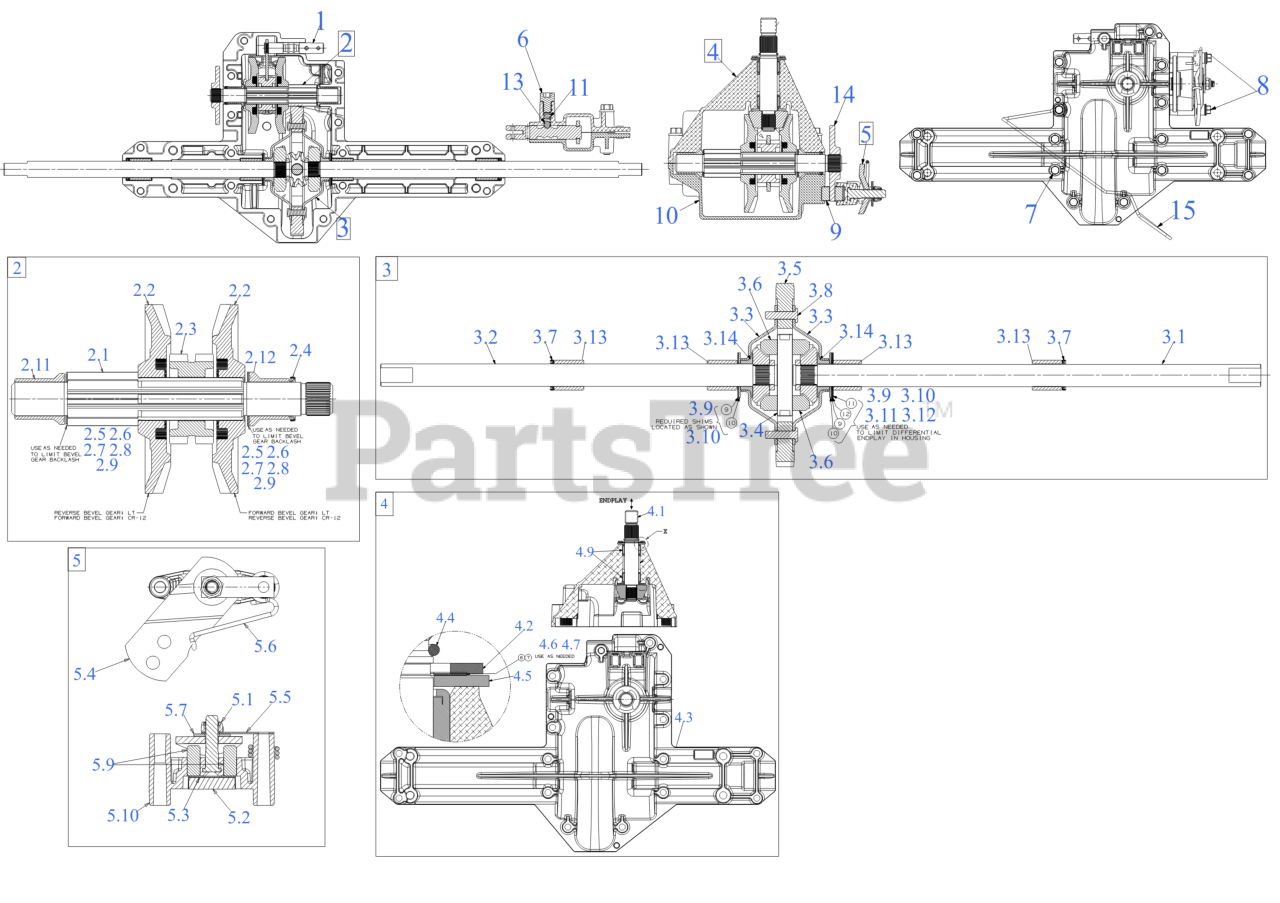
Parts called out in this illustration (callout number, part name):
1	DETENT SHAFT ASSEMBLY
2	FWD/REV SHAFT ASSEMBLY
2.1	Not Serviceable/ Order Complete Assembly
2.2	BEVEL GEAR 42T SPLINE
2.3	CLUTCH COLLAR
2.5	SHIM WASHER 0.627x1.030x0.030
2.6	SHIM WASHER 0.627x1.030x0.040
2.7	SHIM WASHER 0.627x1.005x0.020
2.8	SHIM WASHER 0.627x1.010x0.036
2.9	SHIM WASHER 0.627x1.010x0.025
2.11	FLANGE BEARING .625x.750x.938
2.12	FLANGE BEARING .625x.750x.750
3	DIFFERENTIAL
3.1	Not Serviceable/ Order Complete Assembly
3.2	Not Serviceable/ Order Complete Assembly
3.3	Not Serviceable/ Order Complete Assembly
3.4	CROSS PIN .500 x 2.75
3.5	Not Serviceable/ Order Complete Assembly
3.6	MITER GEAR 10T
3.8	Not Serviceable/ Order Complete Assembly
3.9	SHIM WASHER 0.755x1.505x0.030
3.10	THRUST WASHER 0.755x1.505x0.060
3.11	SHIM WASHER 0.755x1.505x0.010
3.12	SHIM WASHER 0.755x1.505x0.022
3.13	SLEEVE BEARING
3.14	FLANGE BEARING
4	UPPER HOUSING ASSEMBLY
4.1	INPUT SHAFT ASSEMBLY
4.1	THRUST WASHER
4.1	INPUT PINION GEAR 14T
4.3	Not Serviceable/ Order Complete Assembly
4.5	THRUST WASHER
4.6	SHIM WASHER 0.627x1.010x0.010
4.7	SHIM WASHER 0.627x1.010x0.007
4.9	NEEDLE BEARING
5	BRAKE ASSEMBLY
5.1	HEX JAM LOCK NUT 5/16-24
5.3	BRAKE PAD PLATE
5.4	BRAKE ACTUATING ARM
5.5	ANTI ROTATION BRACKET
5.6	TORSION SPRING
5.7	THRUST WASHER
5.9	ACTUATING PIN
5.10	BRAKE YOKE
6	SHCS:M8X1.25:10:GB/T 699-1999
7	HXFLG:M6X1:40:GR8.8
8	HXFLG:M6X1:58:GR8.8
10	HOUSING ASSEMBLY (LOWER)
11	DETENT SHAFT SPRING
13	DETENT BALL .250
14	BRAKE DISC
15	DRIVE BELT KEEPER
